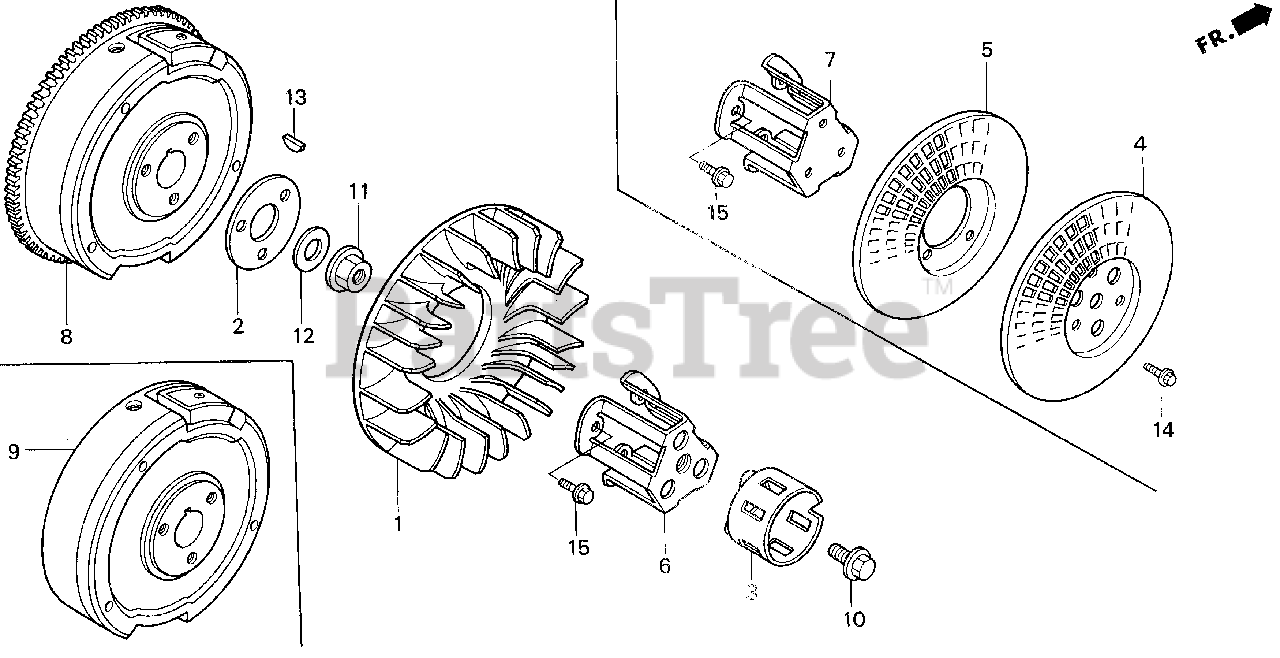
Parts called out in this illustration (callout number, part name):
1	FAN, COOLING
2	PLATE, COOLING FAN SETTING
4	GRID, SCREEN
5	GRID, SCREEN (P.T.O.)
7	HOLDER, SCREEN GRID
8	FLYWHEEL
11	NUT, FLANGE (20MM)
12	WASHER (20MM)
13	KEY, SPECIAL WOODRUFF (25X18)
14	BOLT, FLANGE (6X12)
15	BOLT, FLANGE (8X16)
